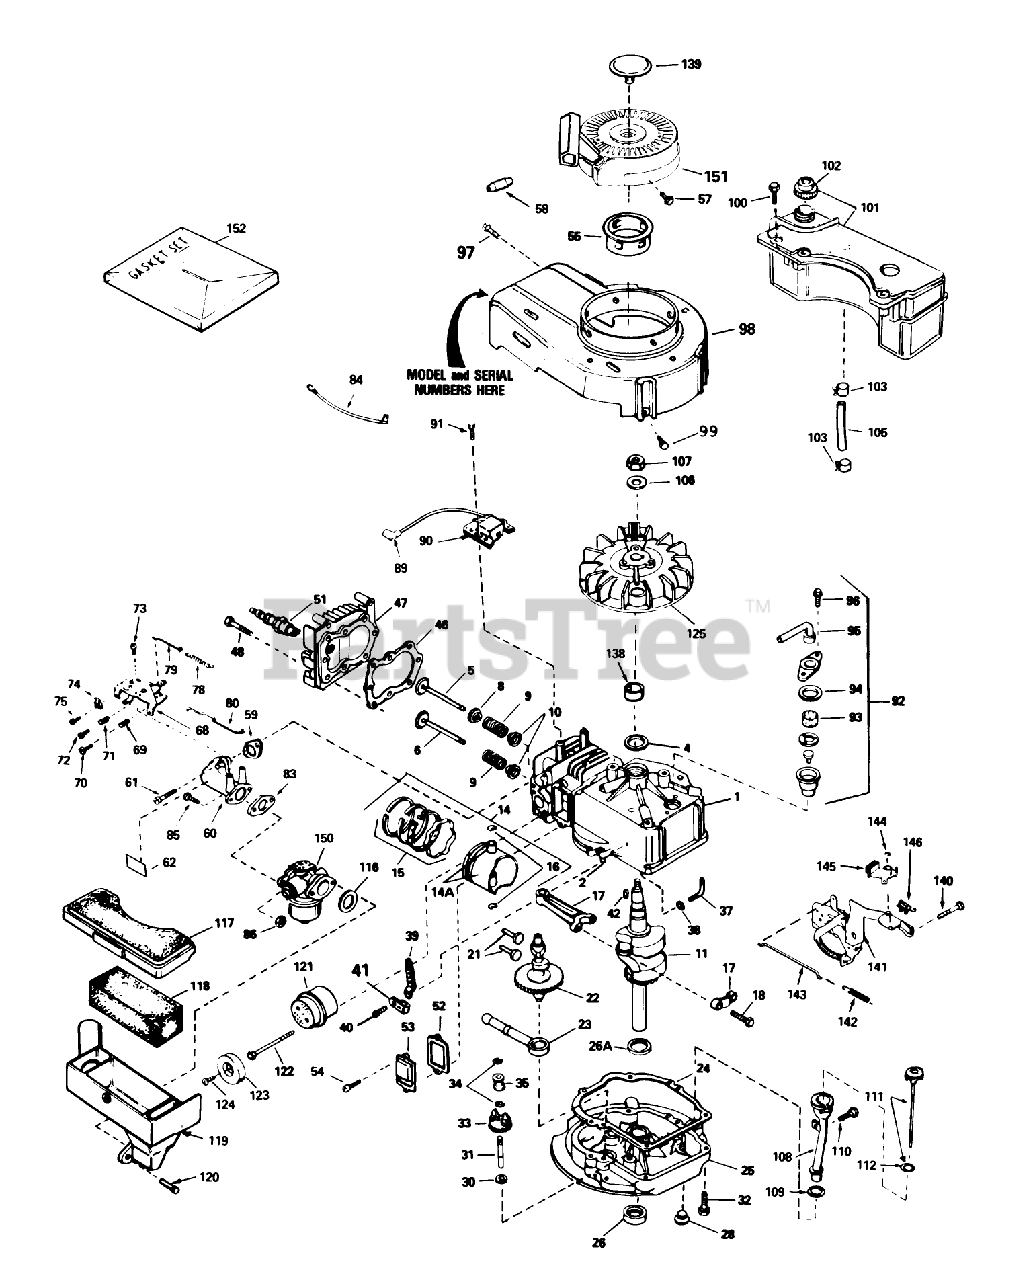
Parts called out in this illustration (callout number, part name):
1	Cylinder Assy. (Incl. #24)
2	Pin-Dowel
4	Seal-Oil
5	Valve, Intake (Std.) (Incl. Ref. #40)
5	Valve, Intake (1/32" oversize)(Incl. No. 40)
6	Valve, Exhaust (Std.)(Incl. No. 40)
6	Valve, Intake (1/32" oversize)(Incl. No. 40)
8	Seal Assy., Intake
9	Spring-Valve
10	Cap-Valve, Spring
11	Crankshaft
14	Piston, Pin Ring Assy. (Std.) (Incl. Ref. #13A, 14 15)
14	Piston, Pin Ring Assy. (.010 oversize) (Incl. Ref. #13A, 14 15)
14	Piston, Pin Ring Assy. (.020 oversize) (Incl. Ref. #13A, 14 15)
14A	Piston Pin Assy. (Incl . Ref. . #14) (Std.)
14A	Piston Pin Assy. (Incl. Ref. #14) (.010 Oversize)
14A	Piston Pin Assy. (.020 oversize) (Incl. Ref. #14)
15	Ring Set (Std.)
15	Ring Set (.020" OS)
15	Ring Set (.010" OS)
16	Ring-Retaining, Piston Pin
17	Rod Assy., Connecting (Incl. Ref. #17)
18	Bolt-Rod, Connecting
21	Lifter-Valve
22	Camshaft(Mech.Comp. Release)
23	Oil Pump ASM
24	Gasket
25	Flange-Mounting (Incl. Ref. #26, 27 39)
26	Seal-Oil
26A	Washer-Thrust
28	Plug Oil Drain
30	Washer-Flat
31	Shaft-Governor
32	Screw (1/4-20 x 1-1/4)
33	Governor Gear ASM
34	Ring-Retaining
35	Spool-Governor
37	Rod, Governor (Incl. No. 36)
38	Washer-Flat
39	Governor Lever
40	Screw
41	Clamp-Lever, Governor
42	Key-Flywheel
46	63573 GIL 42 SNWTHW
47	Head-Cylinder
48	Screw (5/16-18x1-1/2)
51	Plug, Spark (Autolite 458, Champion J-19LM or equiv.)
52	Gasket-Breather
53	Cover-Valve
54	Screw
55	Hub-Starter
57	Screw, Hex Hd.
58	Retainer-Starter Rope
59	Gasket-Intake
60	Pipe-Intake (Incl. Ref. #59)
61	Screw (1/4-20 x 1)
62	Decal-Primer
68	Control Assy.-Remote Speed (Incl. Ref. #69 thru 72 76)
69	61709/GIL1515A/95-5
70	Screw
71	Spring-Compression
72	Screw
73	Screw (10-24 x 9/16)
74	Conduit
75	Screw (10-32 x 3/8)
78	Spring Governor
79	2035A67 ADD.ASSEMBL
80	Link-Throttle
83	Gasket
84	Ground Wire
86	Nut and Lock Washer (1/4-28)
89	Cover-Spark Plug
90	Solid State
91	Screw
92	Breather Assy. (Incl. Ref. #46 thru 51)
93	Element-Breather
94	Gasket-Breather
95	Tube, Breaker
96	Screw (10-24 x 9/16)
97	Screw (10-24 x 9/16)
98	Housing-Blower
99	Screw (1/4-20 x 1/2)
100	Screw (10-32 x 35/64)
101	Tank Assembly-Fuel (Incl. Ref. #102)
102	Cap-Fuel
103	Clamp-Line, Fuel
105	Line-Fuel
106	Washer-Belleville
107	Nut-Flywheel
108	Tube-Oil Fill
109	Gasket
110	Screw (10-32 x 1/2)
111	Dipstick-Oil (Incl. Ref. #112)
112	O-Ring
116	Gasket-Cleaner, Air
117	Cover-Air Cleaner
118	Filter-Air Cleaner
119	Body Air cleaner
120	Screw
121	Muffler (Incl. Ref. #122)
122	Screw
123	Cover-Muffler
124	Screw (8-32 x 3/8)
125	Flywheel
138	Spacer
139	Plug Starter
140	Screw (1/4-20 x 3/8)
141	Bracket-S.E. Brake
142	Spring-Extension
143	Link-Control
144	Ring-Retaining
145	Lever-Brake
146	Terminal
150	Carburetor (Incl. Ref. #83)
151	Starter-Rewind
152	Gasket Set
